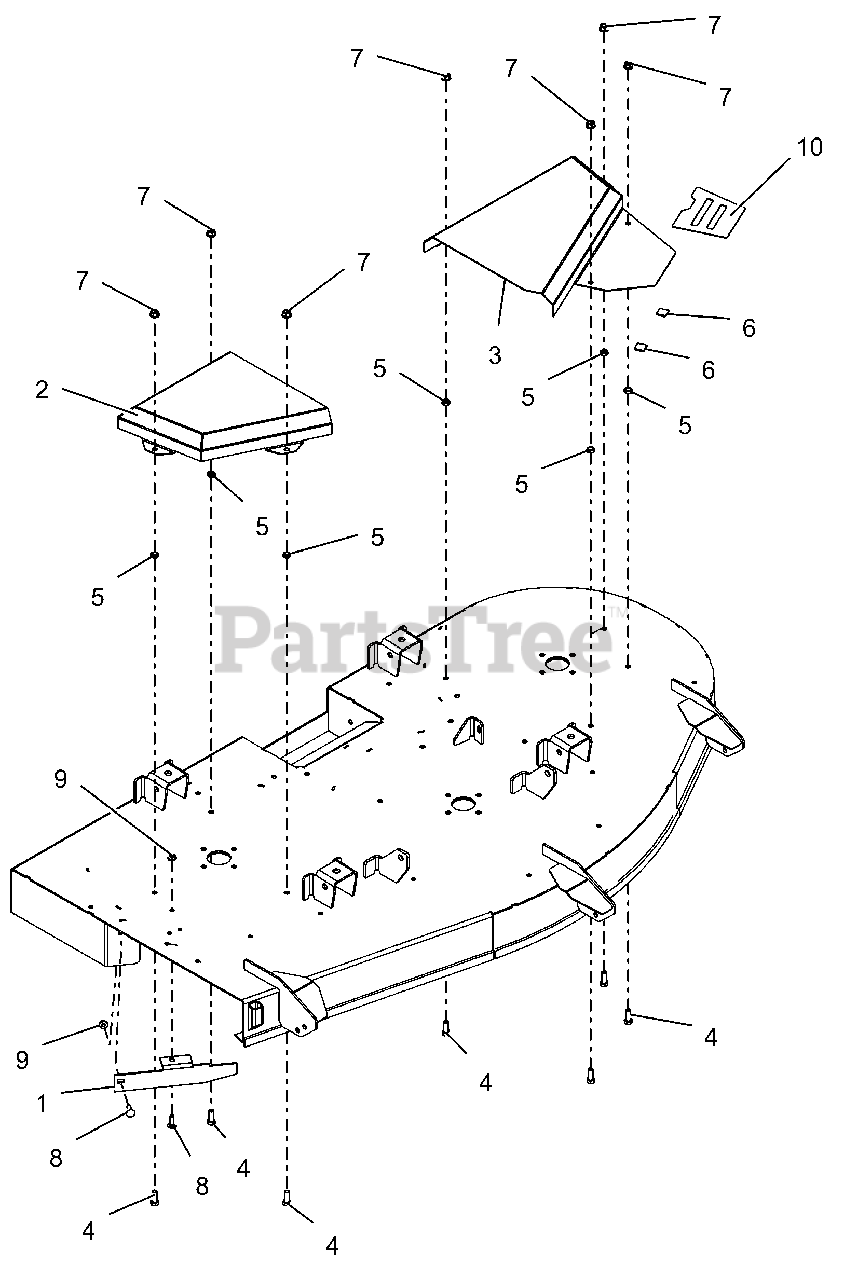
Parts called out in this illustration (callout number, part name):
1	BAFFLE, DISCHARGE 60"
2	COVER, BELT RH 60"
3	COVER, LH BELT 60
4	BLT,HEX .38-16X1.00 G5 ZCC
5	NUT-JAM .375-16 G2 ZCC
7	NUT-LK-CTR-FLG .375-16 GF ZCC
8	BLT,RHSN .31-18X1.00 G5 ZCC
9	NUT,NYL-FLG .31-18 GF ZCC
10	GRIP, TAPE 52-60 BELT COVER
